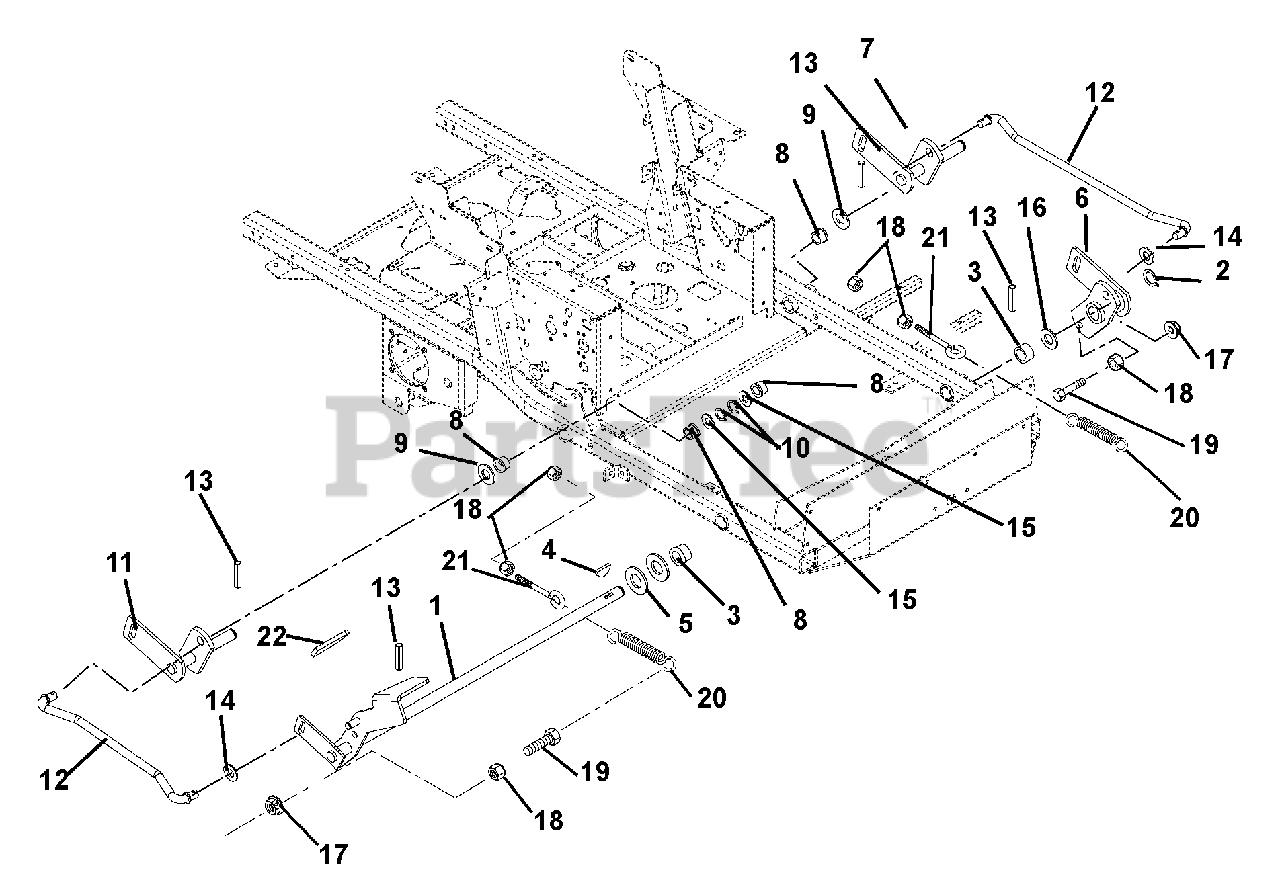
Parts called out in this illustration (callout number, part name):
1	Lift, Mechanical Mower
1	Lift, Hydraulic Mower
2	Ring, Retaining External 1.00 x .078
3	Bushing, 1.00 x 1.12 x .75 x 1.375
4	Key, Woodruff .25 x 1.00
5	Washer, Flat Steel 1.062 x 2.00 x .134
6	Weldment, Lift Arm Front
7	Weldment, Left Hand Rear Lift Arm
8	Bushing, Flange Nylon .762 x 1.00 x .58 x 1.48
9	Washer, Hardened Steel .758 x 1.23 x .031
10	Ring, Retaining External .689 x .077
11	Weldment, Right Hand Rear Lift Arm
12	Rod, Lift Assist
13	Pin-Roll .250 x 1.25 Stainless Steel
14	Washer-Flat-Steel .630 x 1.25 x .062
15	Washer, Flat Steel .755 x 1.25 x .125
16	Washer, Hardened Thrust 1.00 x 1.55 x .03
17	Nut, Locking-Top-Flange .38-16
18	Nut, Hex .38-16
19	Bolt, Hex .38-16 x 1.75 Grade 5
20	Spring, Tension .162 x 1.25 x 8.25
21	Bolt, Eye .375-16 x 2.50
22	Grip, Foot Pedal
